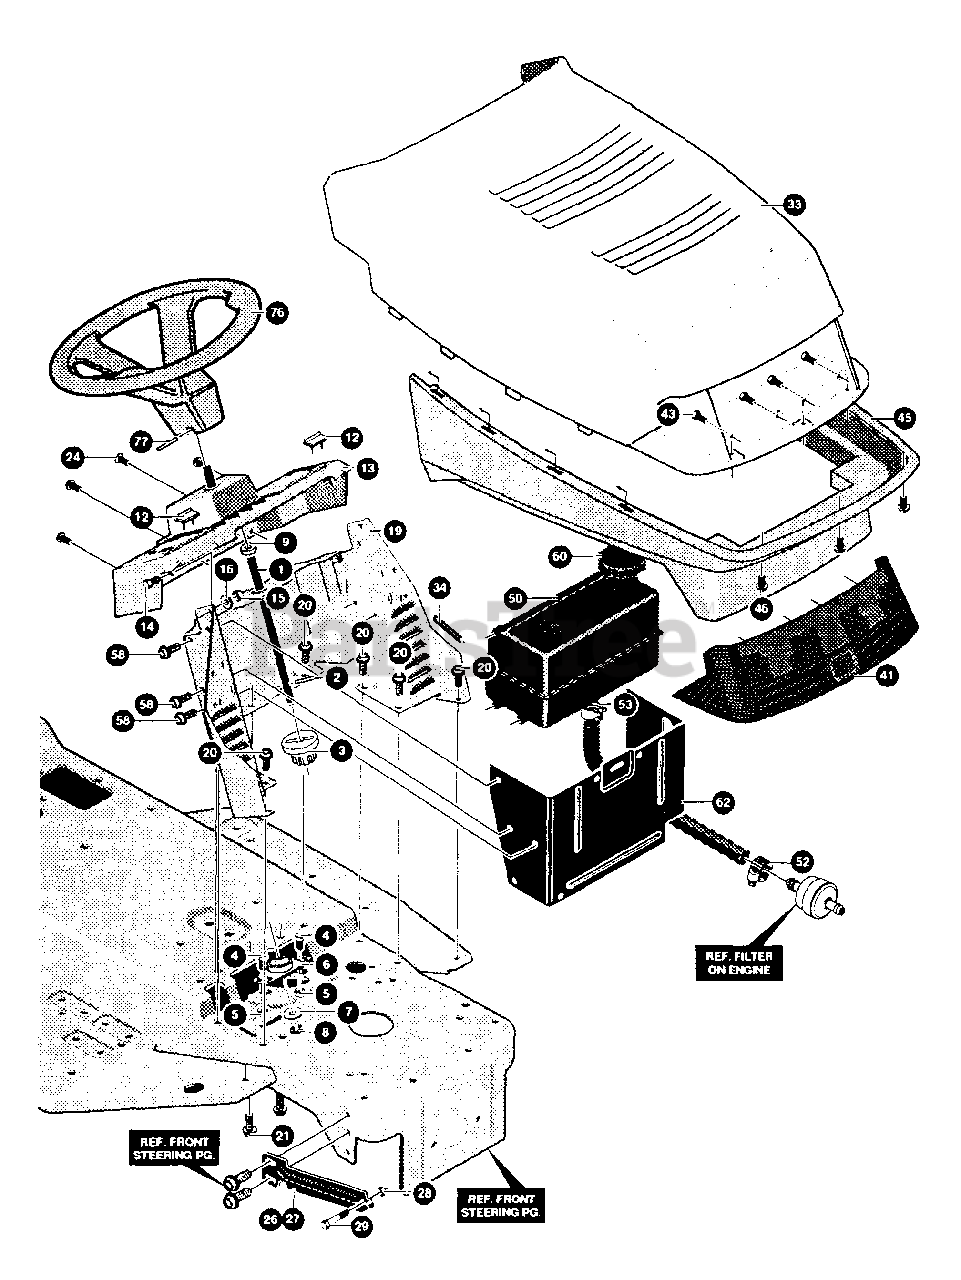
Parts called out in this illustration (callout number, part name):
1	SHAFT STEERING EURO LT SHORT
2	PIN DOWEL STR ERO LT
3	PINION, STEERING
4	SCREW, 5/16-24 X .75 (TO 30-35 FT#)
5	NUT, 5/16-24 HEXWDFLLK
6	BEARING, FLANGED .500ID X OD X .75
7	WASHER, FLAT .504 X .75 X .059
8	RING, RET E .39 X .04TRU5133-50
9	BUSHING STR SHIFT UPPER
12	BUMPER, HOOD/DASH EURO TOP
13	DASH, TALL
14	SCREW, 1/4-20 X .75 HHC
15	NUT, 1/4-20 REGHEXCTRLK
16	WASHER, FLAT .281 X .63 X .065
19	DASH LOWER SHORT LT
20	SCREW, 5/16-18 X .50 WAHHTAP
21	SCREW, 5/16-18 X .37 WAHHTAP
23	SCREW, 1/4-20 X .50 WAHHTAP
24	SCREW, 1/4-20 X .50 PHPNTAP
26	BRACKET, HOOD RH H19/G16
27	BRACKET, HOOD LH
28	NUT, 5/16-18 REGHEXCTRLK
29	BOLT, .500 X .375 HHSH 5/16-18
33	HOOD, UPPER
34	EDGING, WIDE BLK
41	LENS, HOOD SMOKED GREY
43	SCREW, #10 X .50 HHTAPPST
45	GRILLE, MOLD/GREY
46	SCREW, 1/4-14 X .75PHPNHDTAP
50	ASSY GAS TANK 1.5 GAL
52	CLAMP, FUEL LINE
53	CLAMP, HOSE SCREW TYPE
58	SCREW, .25 X .75 X .51 HHWAPLASTITE
60	CAP FUEL 2.5" THROAT
62	HEAT SHIELD ERO 1.5 & 3 GAL
76	STEERING WHEEL
77	PIN, SPRING .250DIA X 2.00LG HVPL
